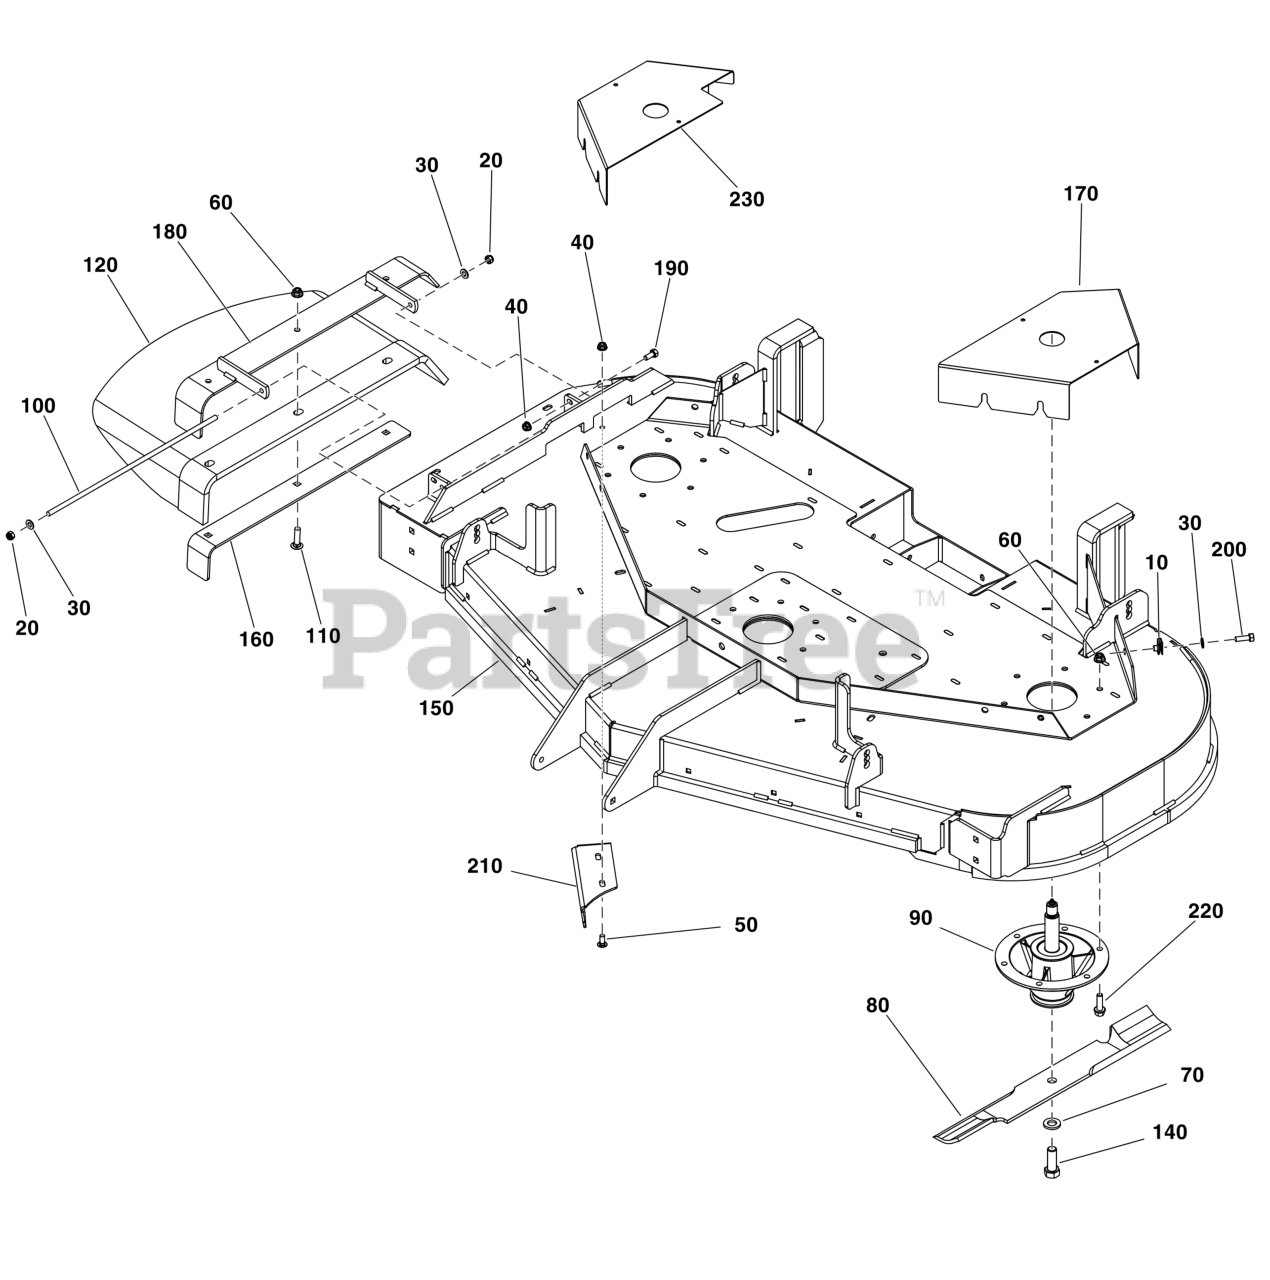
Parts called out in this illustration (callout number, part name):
10	BODY CLIP, 5/16-18 X
20	NUT, 5/16-24 HEX NYLO
30	WASHER
40	NUT
50	BOLT, 5/16-18 X 3/4",
60	NUT, 3/8-16 HEX NYLOCK
70	WASHER, 5/8" YZ
80	BLADE SET, 61 DECK (3)
90	ASSEMBLY-SPINDLE
100	ROD
110	BOLT, 3/8-16 X 1-1/2
120	CHUTE, RUBBER DISCHARGE (5104442)
140	BOLT
150	DECK SHELL W/ DECALS, SRS Z3X-60 (5422814B)
160	PLATE, SUPPORT
170	GUARD, Pulley, Left
180	FRAME, Chute
190	BOLT, 5/16-18 X 3/4"
210	DEFLECTOR
230	GUARD, Pulley, Right
